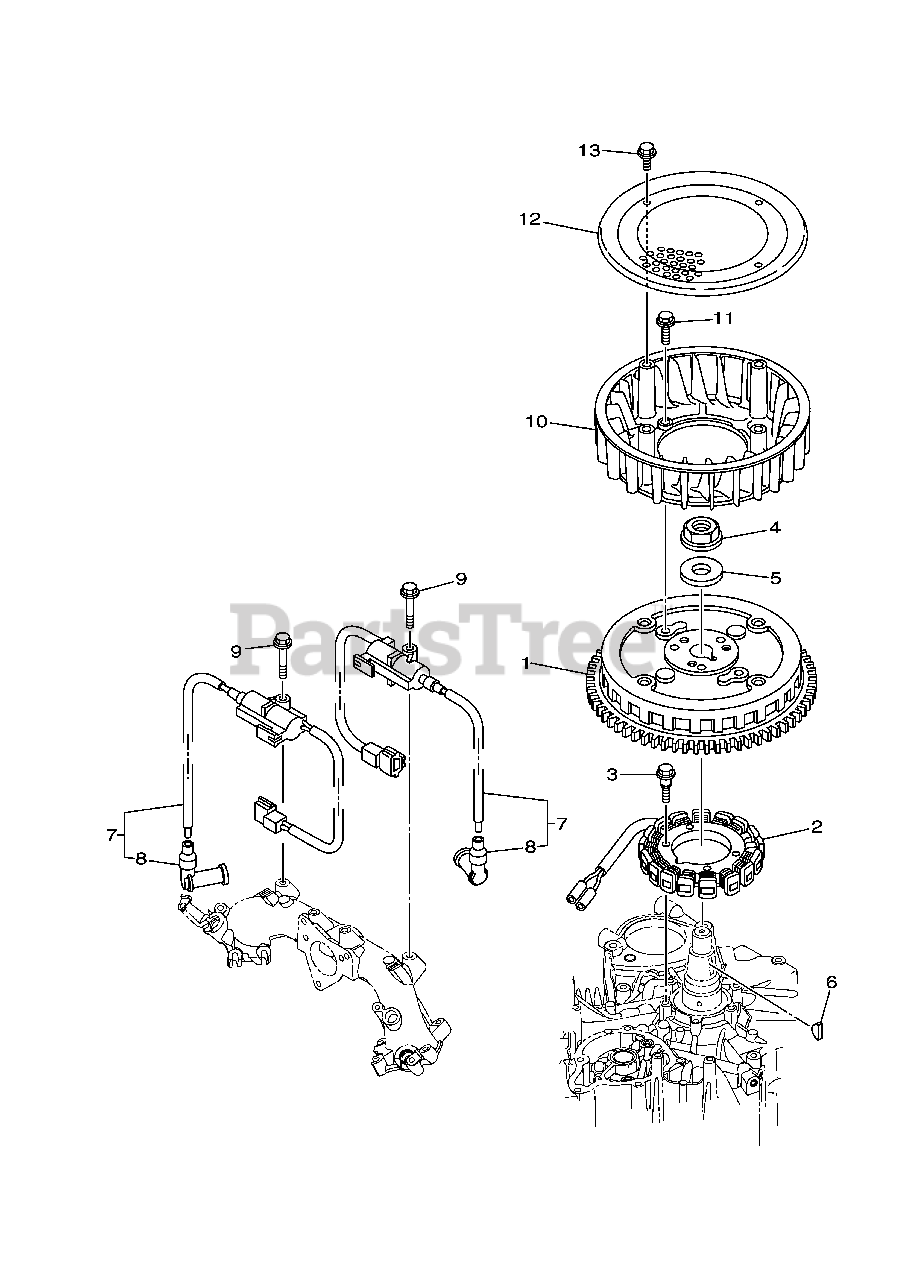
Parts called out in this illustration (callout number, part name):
1	ROTOR ASSY
2	STATOR ASSY
5	WASHER, PLATE
6	KEY, WOODRUFF
7	IGNITION COIL ASSY
8	PLUG CAP ASSY
9	BOLT, FLANGE
11	BOLT, FLANGE
13	BOLT, FLANGE
